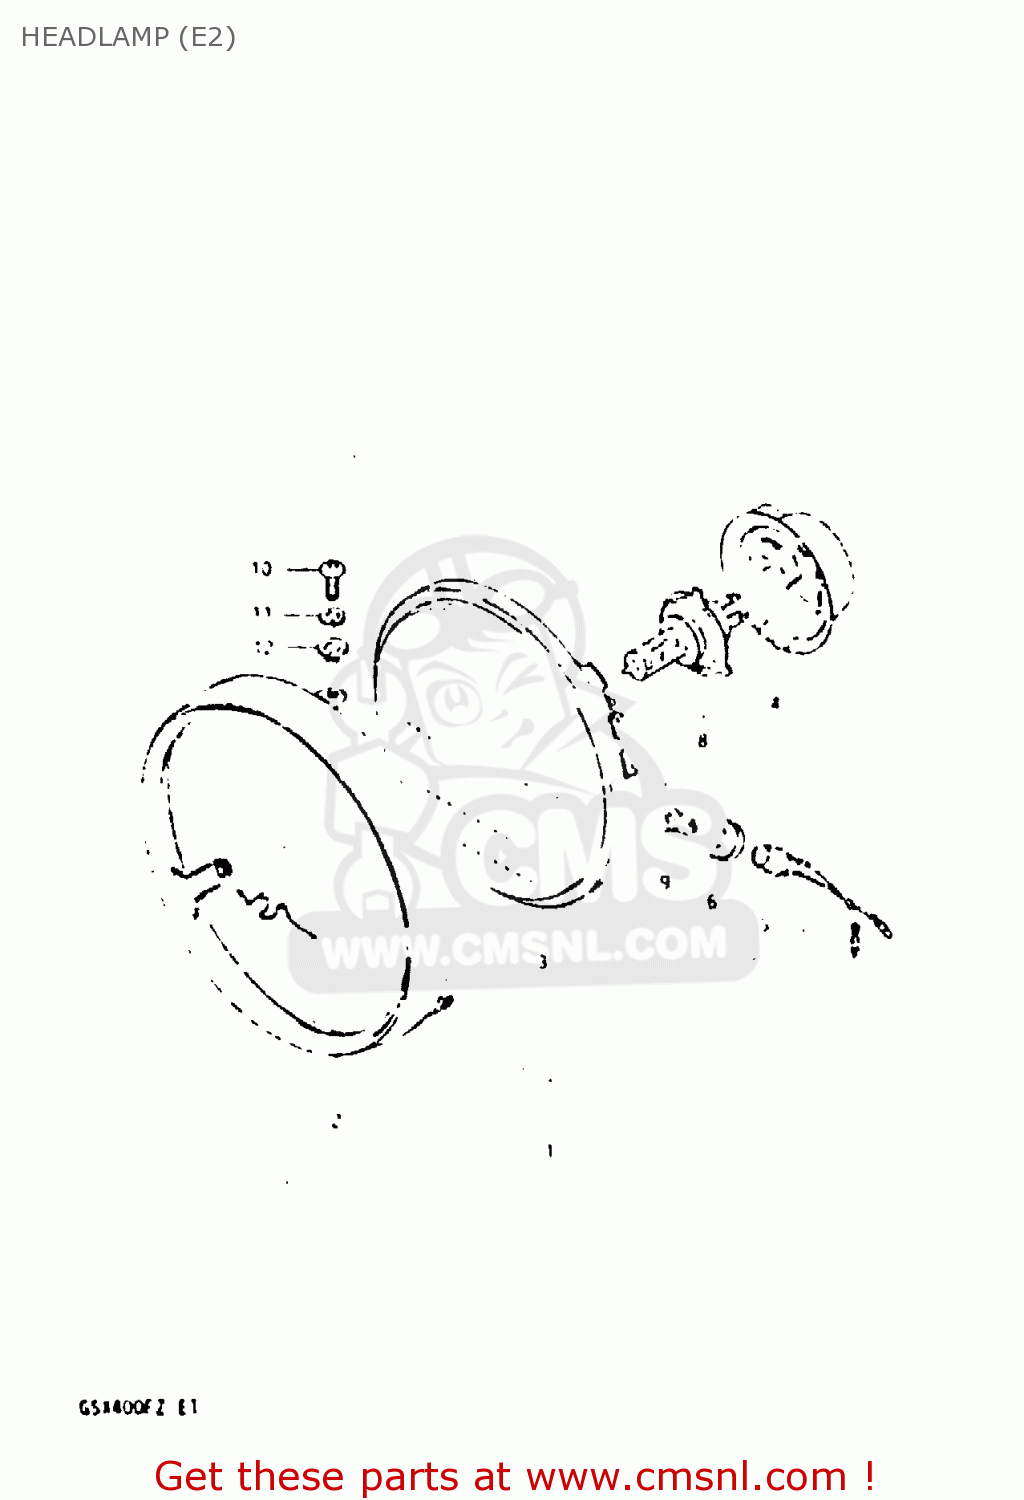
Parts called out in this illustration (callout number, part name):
1	HEADLAMP ASSY
2	RIM
3	LAMP UNIT
4	COVER,SOCKET
5	SOCKET
6	JOINT,RUBBER
7	SPRING
8	BULB(12V60/55W,H4)
9	BULB(12V3.4W,STANLEY,A72A)
10	SCREW
11	WASHER,LOCK
12	WASHER
